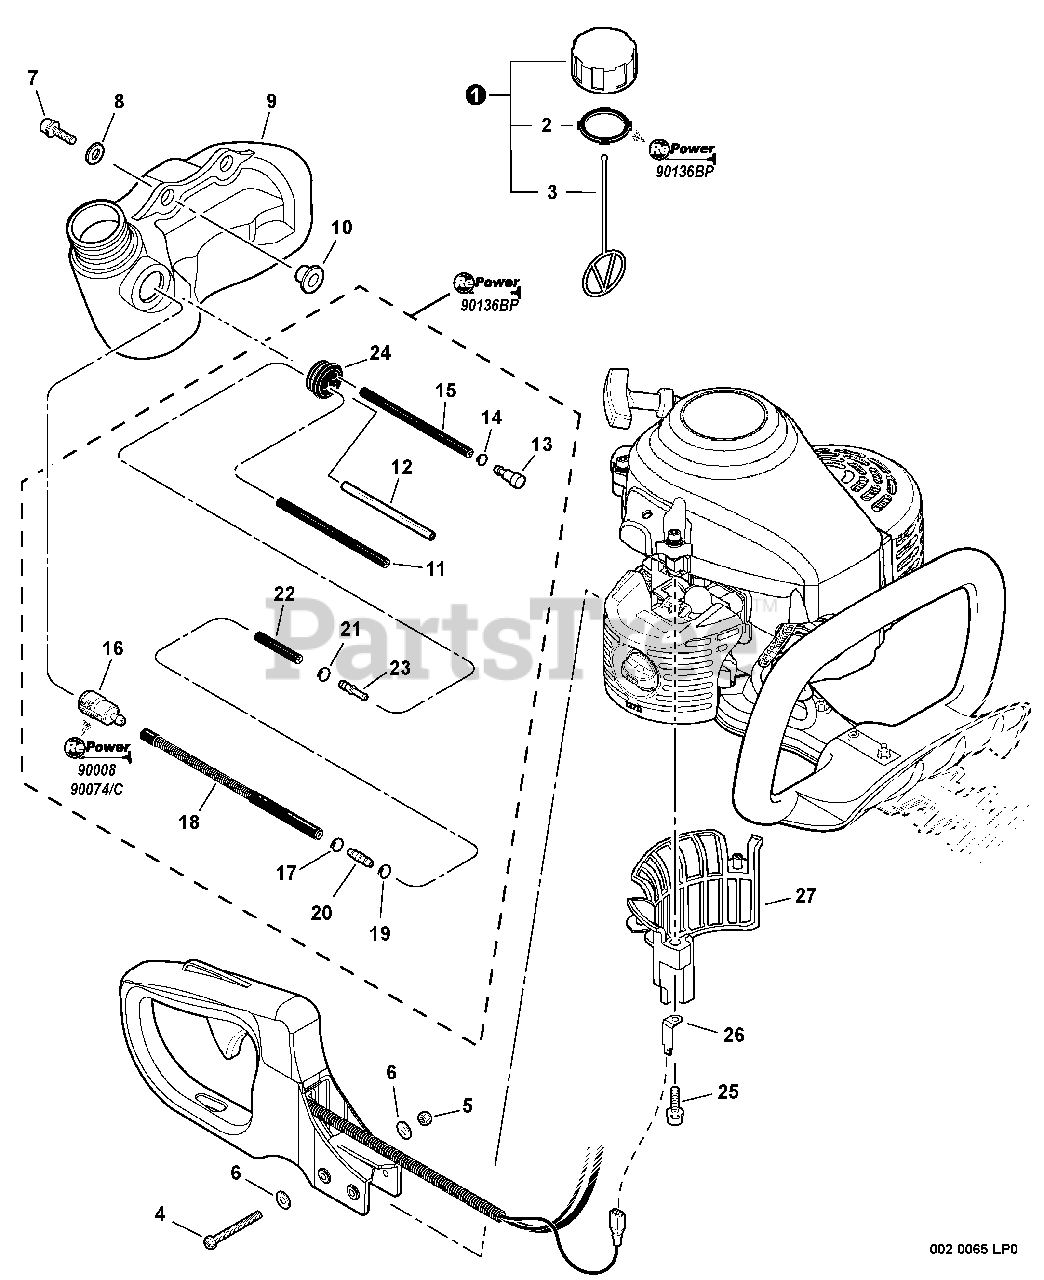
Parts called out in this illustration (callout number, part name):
1	CAP ASSY, FUEL
2	GASKET, FUEL CAP
3	CONNECTOR, CAP L= 123
4	SCREW 5×45
5	NUT, LOCK M5
6	WASHER, FLAT 5.5×10×0.8
7	BOLT 5×20
8	WASHER 5.5×12×0.8
9	TANK, FUEL
10	COLLAR 5
11	PIPE, FUEL 3×5×61 BLACK
12	PIPE, FUEL 3×6×75 CLEAR
13	VENT ASSY
14	CLIP Ø6
15	PIPE, FUEL 3×6×50 BLACK
16	FILTER, FUEL
17	CLIP 6.6 MM
18	PIPE, FUEL 3×7×100 FLEXIBLE
20	CONNECTOR, PIPE
22	PIPE, FUEL 3×6×35 BLACK
23	CONNECTOR, PIPE Ø5ר3.5
24	GROMMET, FUEL
25	BOLT 5×16
26	CONNECTOR
27	SHIELD, DEBRIS
28	FILTER KIT - REPOWER
29	TUNE-UP KIT - REPOWER
30	FUEL SYSTEM KIT
